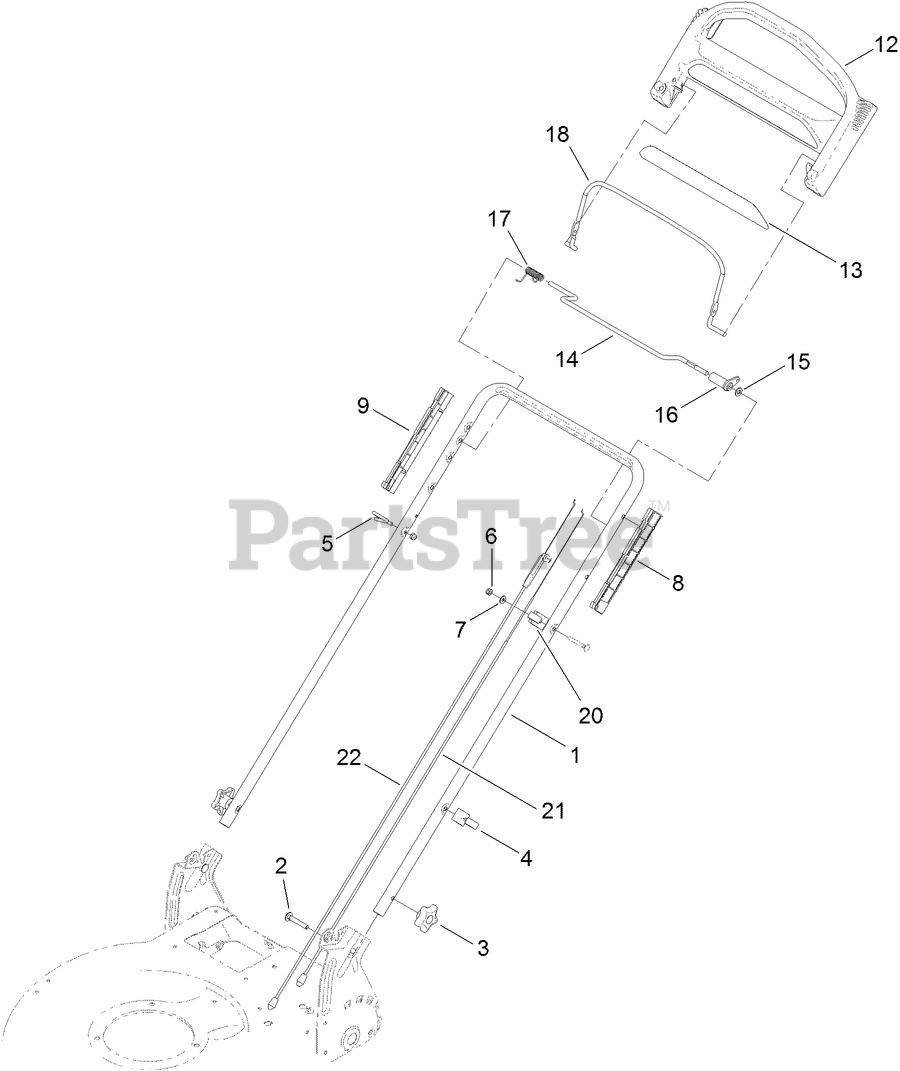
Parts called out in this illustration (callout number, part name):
2	BOLT-CARR
3	KNOB-HANDLE
4	GUIDE-CABLE
5	GUIDE-ROPE
6	NUT-LOCK, NI
7	WASHER-FLAT
8	GUIDE-LH
9	GUIDE-RH
12	HANDLE-CONTROL
13	DECAL-HANDLE
15	WASHER-PLAIN
16	LEVER-TRACTION
21	CABLE-TRACTION
22	CABLE-BRAKE
